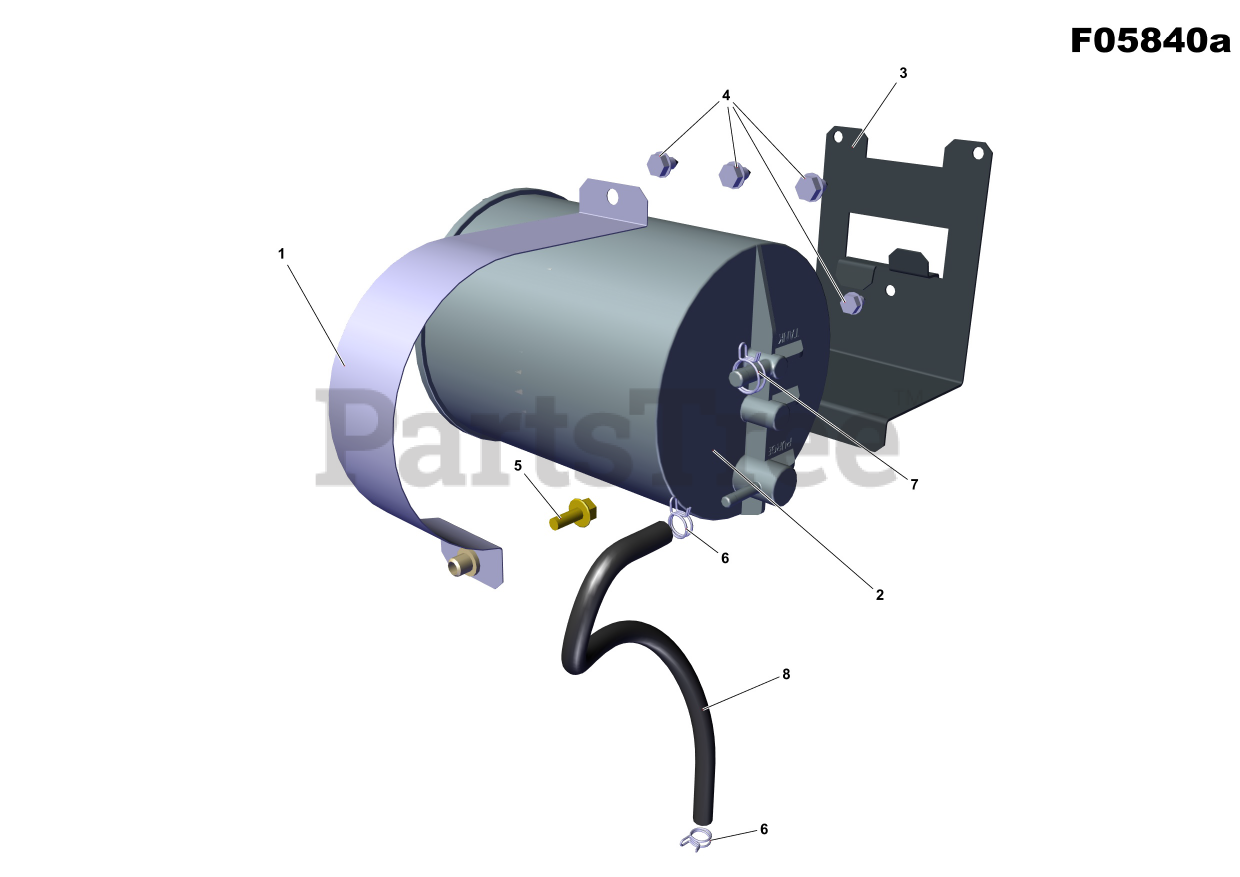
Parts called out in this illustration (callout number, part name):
2	CARBON CANISTER
3	Bracket Canister
6	Spring clamp D8.3/8.8
8	Flexible hose D4.5x9.5
